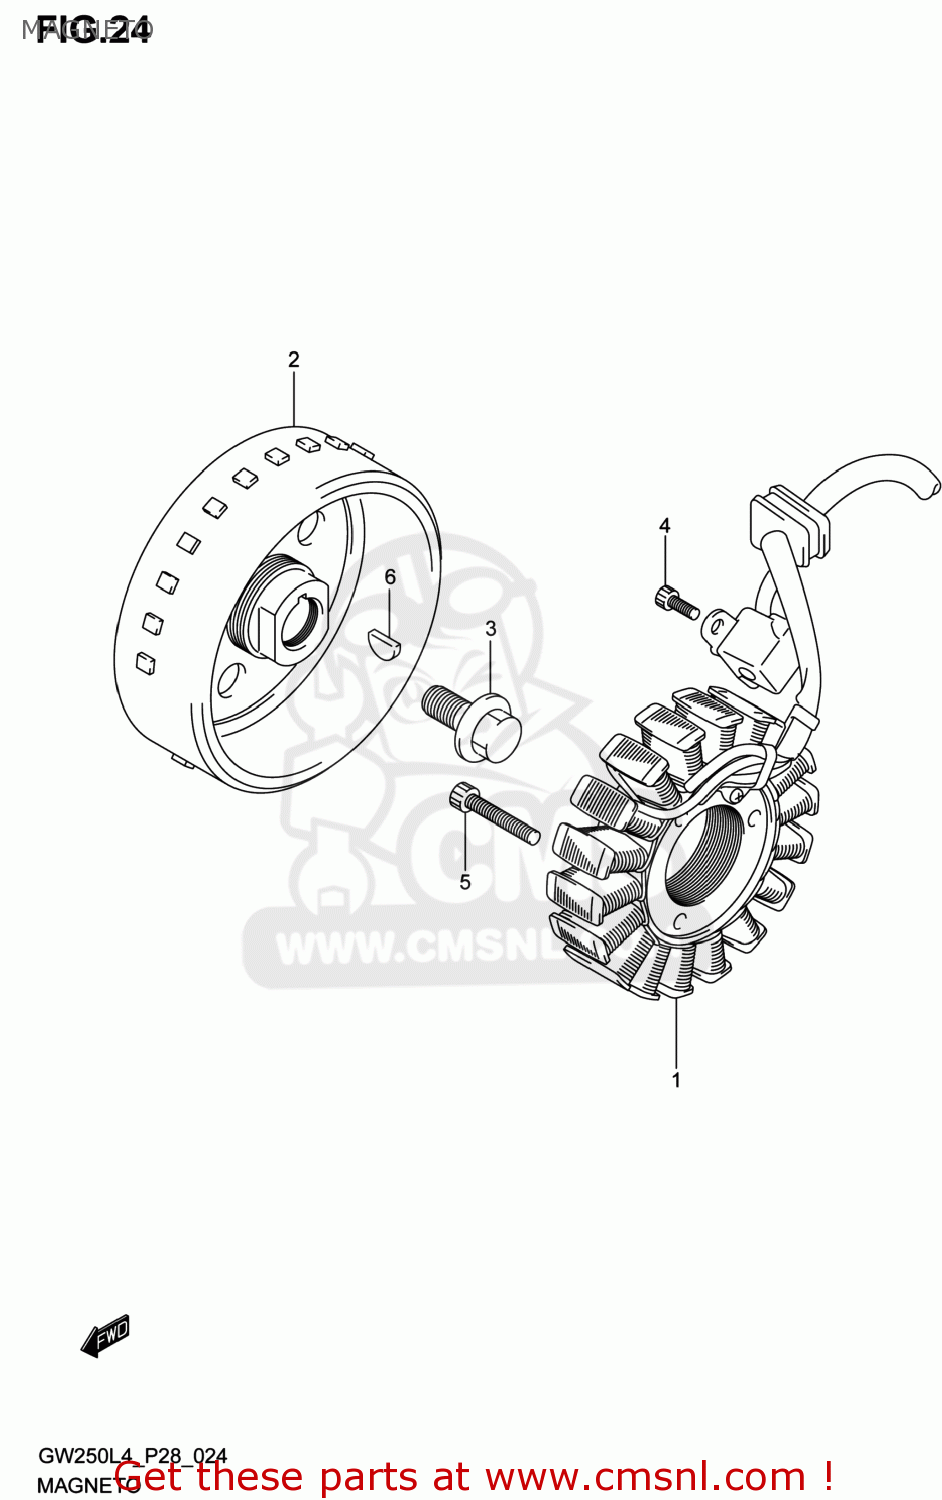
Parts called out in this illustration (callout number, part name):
1	STATOR ASSY
2	ROTOR ASSY
3	BOLT,MAGNETO ROTOR
4	BOLT
5	BOLT
6	KEY
